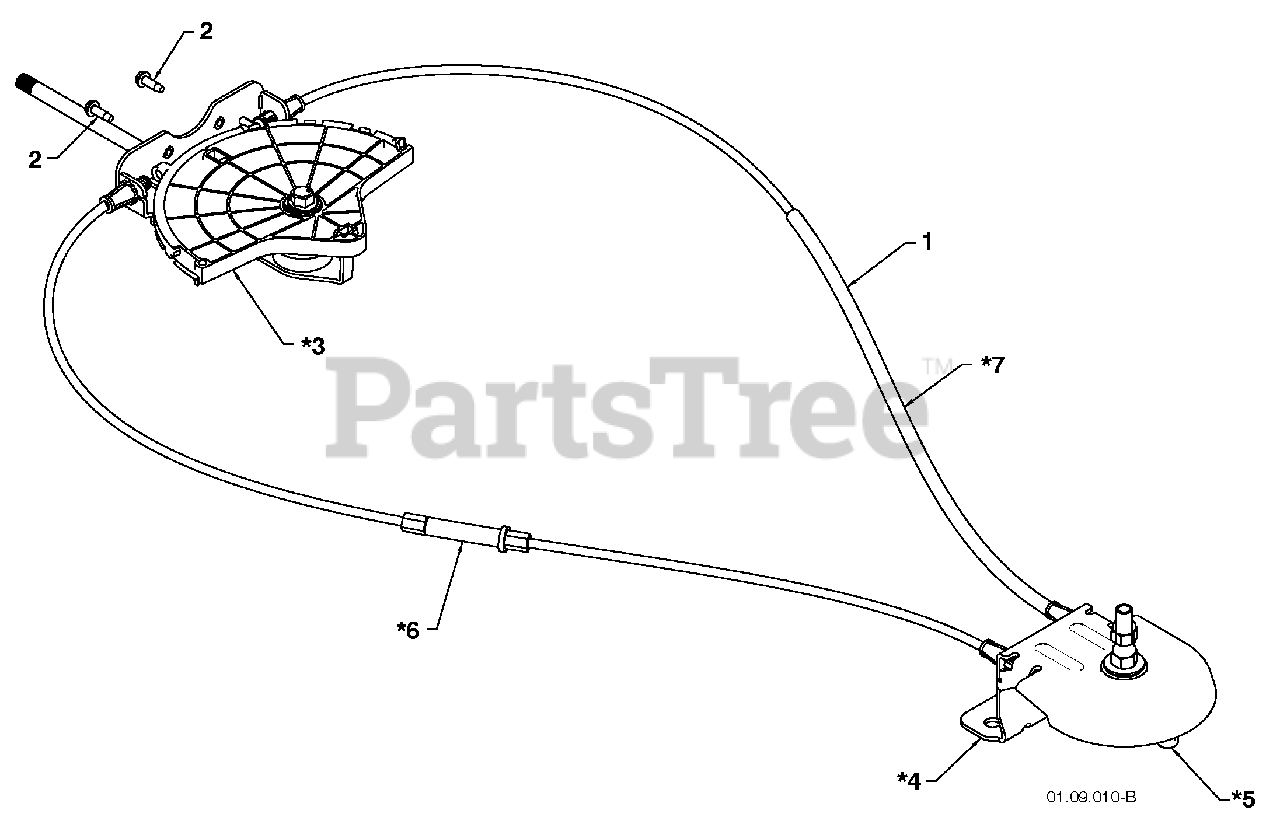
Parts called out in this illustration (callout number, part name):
1	LEVER/CABLE ROTATOR ASSEMBLY
2	SCREW 10-24 X .625
3	ROTATOR HEAD
4	ROTATOR PIVOT BRACKET
5	PULLEY PIVOT
6	CABLE ASSEMBLY ADJUSTABLE
7	CABLE ASSEMBLY HEAT SHIELD
